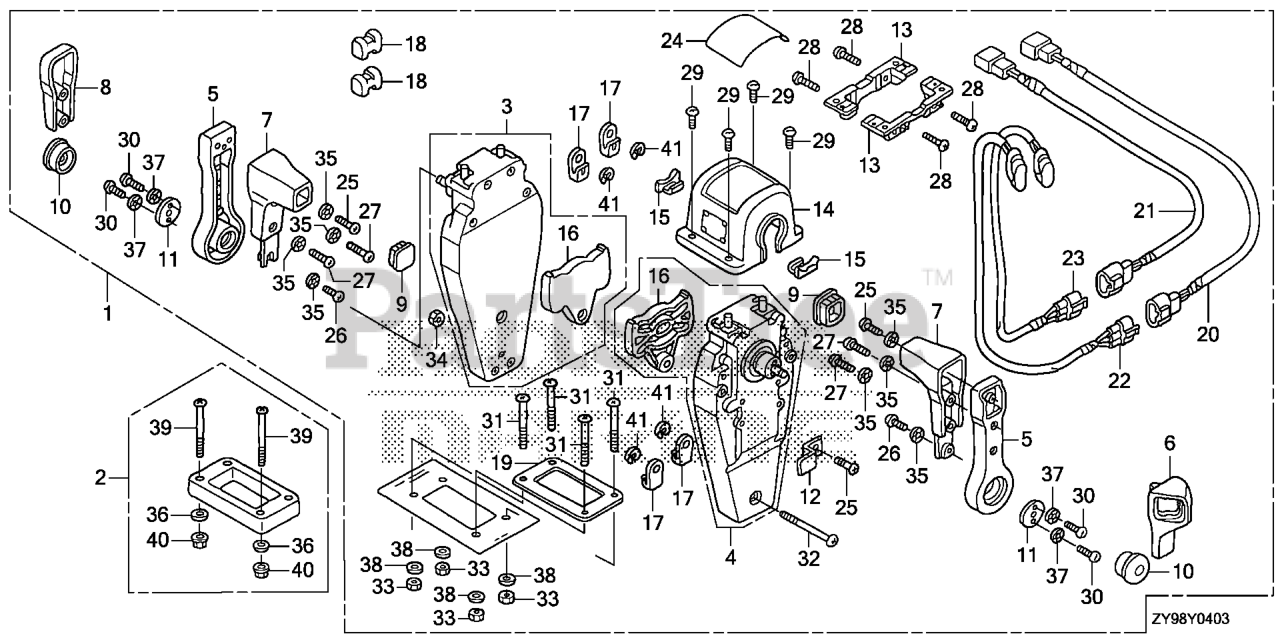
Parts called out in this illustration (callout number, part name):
1	BOX KIT, L. REMOTE CONTROL (TOP MOUNT DUAL)
2	SPACER KIT, REMOTE CONTROL BOX (TOP MOUNT DUAL)
3	HOUSING ASSY., L. (INNER) (TOP MOUNT)
4	HOUSING ASSY., R. (INNER) (TOP MOUNT)
5	HANDLE, REMOTE CONTROL
6	COVER, R. GRIP
7	GRIP, REMOTE CONTROL HANDLE
8	COVER, DUAL GRIP
9	CAP, GRIP
10	BUTTON, THROTTLE
11	PLATE, HANDLE
12	PLATE, CABLE CLAMP
13	BRACKET, REMOTE CONTROL HOUSING
14	HOUSING, DUAL REMOTE CONTROL BOX
15	HOUSING, LEAD
16	PLATE, DWELL
17	TERMINAL, CABLE
18	SPACER, CABLE CLAMP
19	GASKET, DUAL
20	SUB-HARNESS ASSY., POWER TRIM-TILT (A)
21	SUB-HARNESS ASSY., POWER TRIM-TILT (B)
22	SWITCH ASSY., POWER TRIM-TILT (A)
23	SWITCH ASSY., POWER TRIM-TILT
24	MARK, REMOTE CONTROL (DUAL)
25	SCREW, PAN (5X16)
26	SCREW, PAN (5X10)
27	SCREW, PAN (5X20)
28	SCREW, PAN (5X18)
29	SCREW, PAN (4X10)
30	SCREW, PAN (6X18)
31	SCREW, PAN (5X40)
32	SCREW, PAN (5X55)
33	NUT, HEX. (5MM)
34	NUT, HEX. (5MM)
35	WASHER, LOCK (5MM)
36	WASHER, PLAIN (5MM)
37	WASHER, LOCK (6MM)
38	WASHER, PLAIN (5MM)
39	SCREW, PAN (5X65)
40	NUT, HEX. (5MM)
41	E-RING (6MM)
